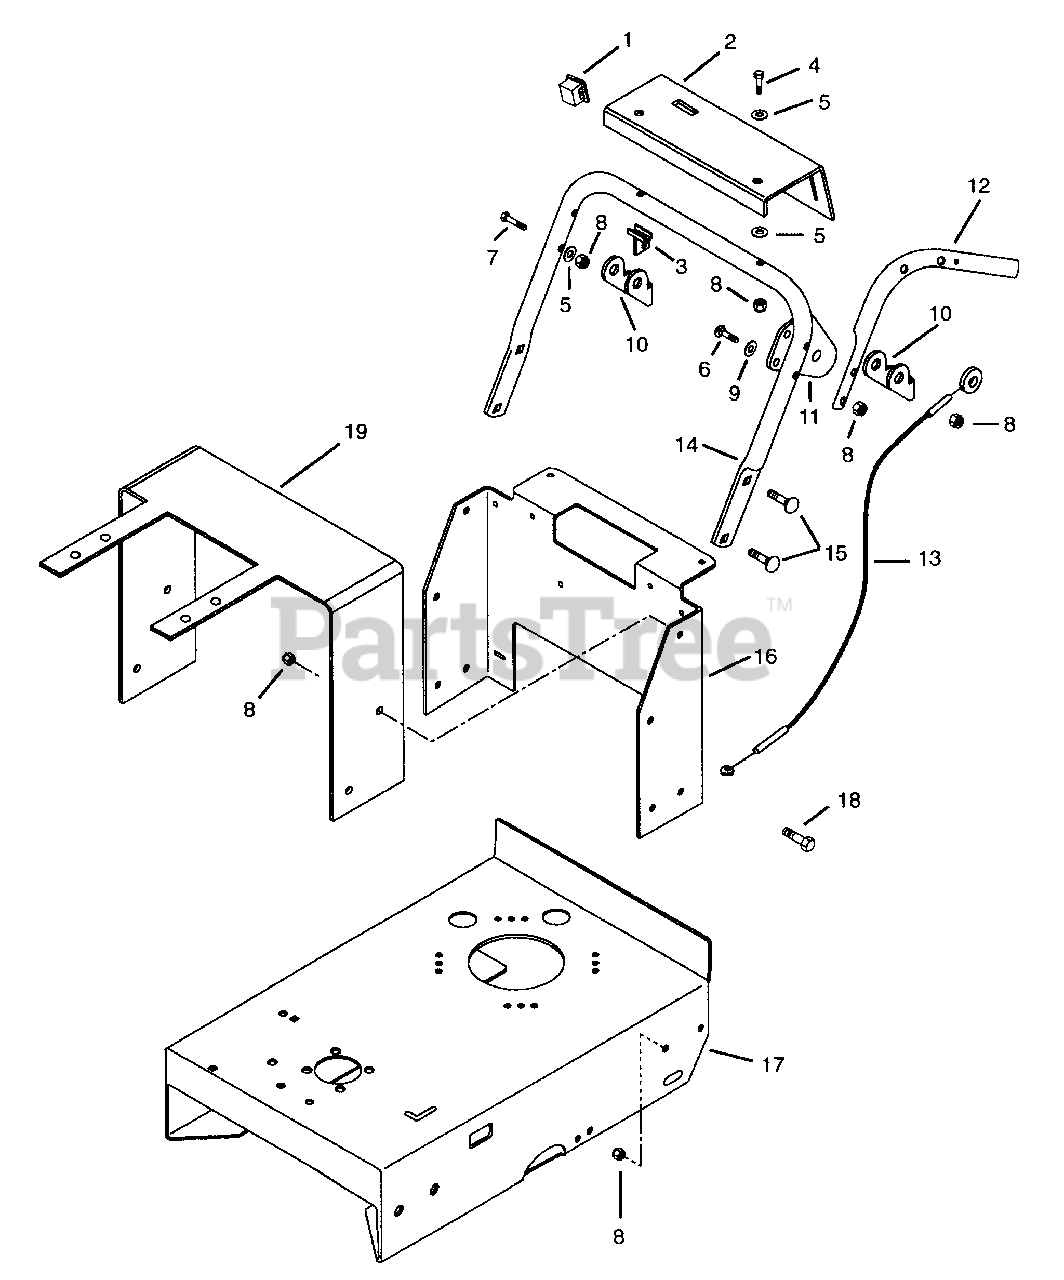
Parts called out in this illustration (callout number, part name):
1	Switch, Blank
2	Panel, Instrument
3	Weldment, PTO Lever Mounting
4	Bolt-Hex .38-16 x 2.00 Grade 5
5	Washer-Flat-Steel .406 x .812 x .065
6	Bolt-Round Head Square Neck .38-16 x 2.25
7	Bolt-Hex .38-16 x 2.25 Grade 5
8	Nut-Locking-Nylon .575-16
9	Washer-Flat-Steel .390 x .750 x .125
10	Bracket, Handlebar Cable
11	Speed Control Plate
12	Handlebar Left Hand
13	Cable, Hand Control, Transmission Left Hand
14	Tube, Handlebar Mounting
15	Bolt-Round Head Square Neck .38-16 x 1.00
16	Rear Frame
17	Main Frame
18	Bolt-Hex .38-16 x 1.00
19	Bracket, Oil Cooler
